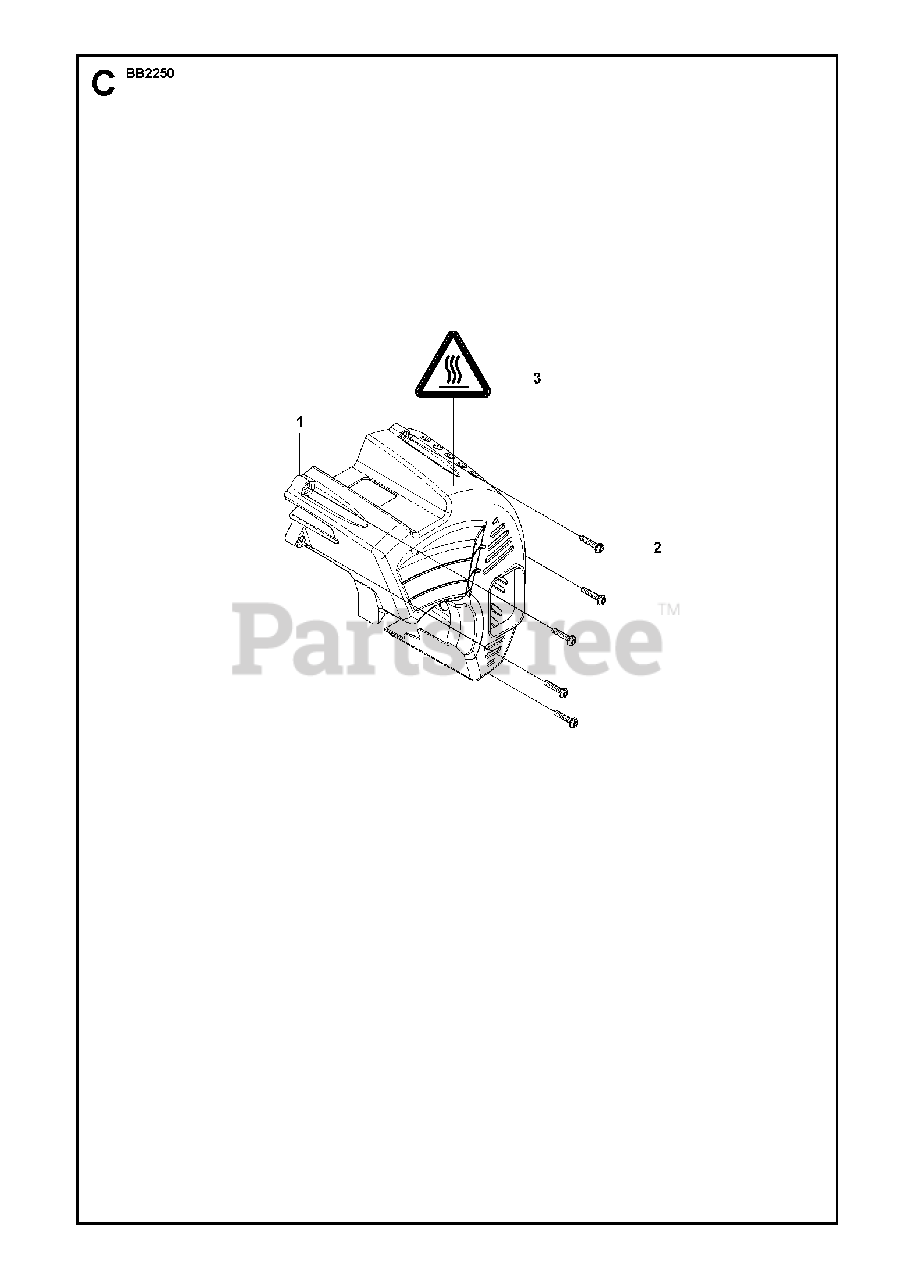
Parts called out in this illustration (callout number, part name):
1	ENGINE COVER
2	SCREW
3	RP_LABEL, HOTMARK
